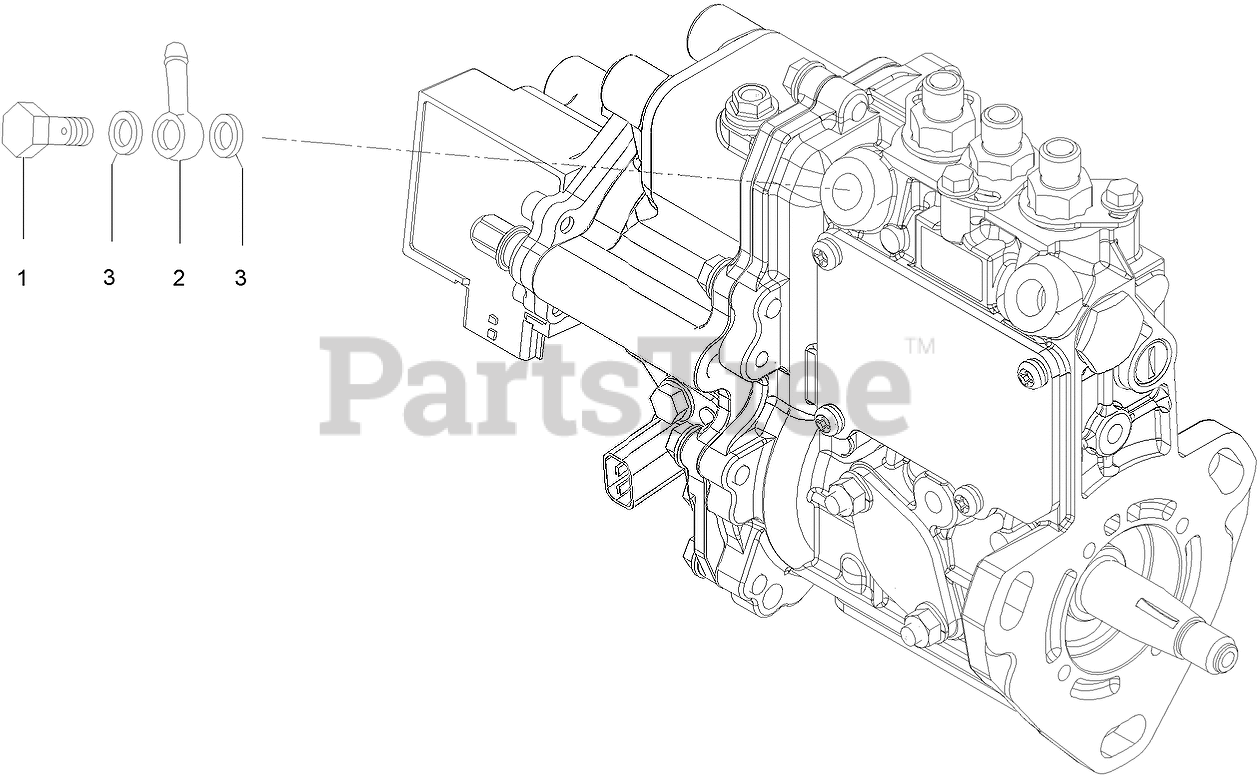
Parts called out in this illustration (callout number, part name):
1	BOLT-PIPE JOINT
2	JOINT-PIPE
3	WASHER-SEAL
